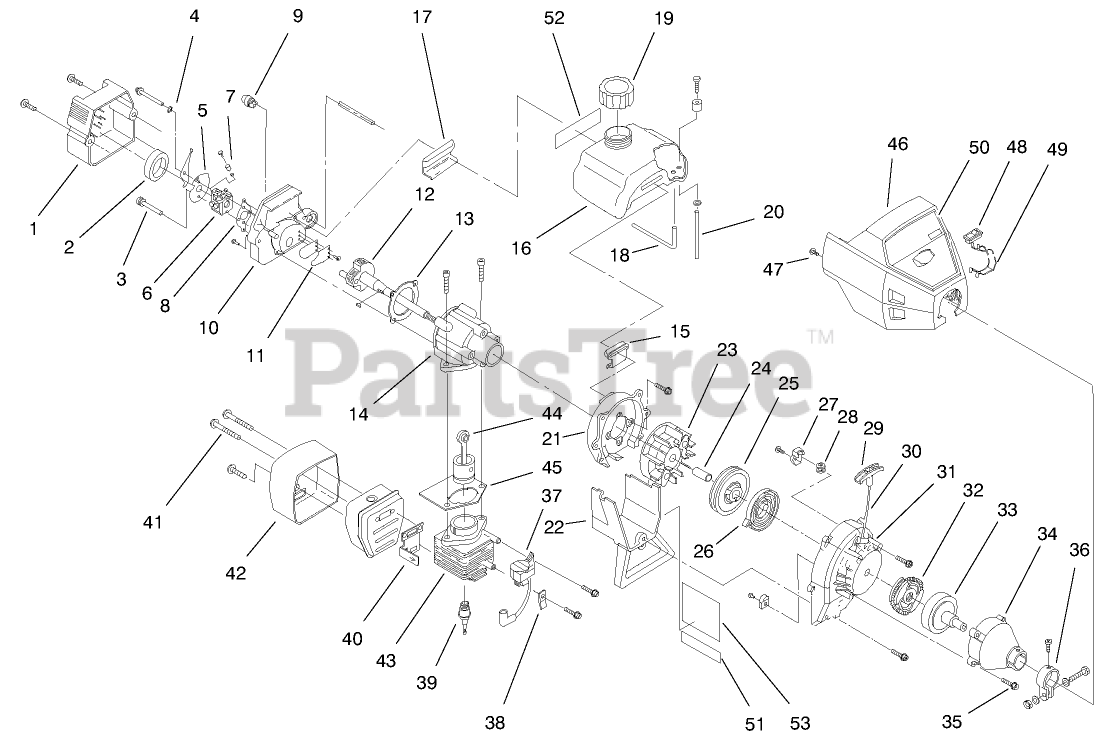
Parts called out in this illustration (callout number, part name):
1	Carburetor/Air Cleaner Asm. (Incl. Ref. #2)
2	FILTER - AIR CLEANER
3	ASSEMBLY - MOUNTING BOLT
4	WASHER - WAVEY
5	LEVER - CHOKE & PLATE
6	Carburetor Asm.
7	THROTTLE ADJ ASM
7	ASM - THROTTLE ADJUSTMENT
8	CARBURETOR GASKET(10 PER PACK)
9	PRIMER & HOSE ASM
10	Carburetor Mount Asm.
11	ASSEMBLY - REED
12	ASM - POWER SHAFT
13	CARB MT GASKET (10-PK)
14	Crankcase Service Asm. (Incl. Ref. #12)
15	FRONT MOUNTING PAD
16	Fuel Tank Asm. (Incl. Ref. #18-20)
17	REAR MOUNTING PAD
18	ASSEMBLY - RETURN LINE
19	FUEL TANK CAP
20	FUEL LINE ASM
21	SHROUD ASM
22	Shroud Extension & Stand
23	FLYWHEEL
24	SPACER
25	RECOIL PULLEY ASM
26	RECOIL SPRING
27	PULLEY RETAINER ASM
28	ROPE GUIDE
29	Handle-Pull
31	ASSEMBLY - STARTER HSG
32	Clutch Rotor Asm.
33	CLUTCH DRUM ASM
34	Clutch Cover Asm.
35	CLUTCH COVER SCREW ASM
36	CLAMP ASM - UPPER
37	Module Asm.
38	GROUND TAB
39	SPARK PLUG
40	GASKET - EXHAUST
41	ASM - MUFFLER MTG BOLT
42	Muffler Asm. (Incl. Ref. #41)
43	ASSEMBLY - CYLINDER
44	PISTON & ROD ASM
45	CYLINDER GASKET
46	COVER - ENGINE
47	Screw
48	SWITCH ASM
49	LEAD WIRE ASM
50	DECAL - TORO
51	Decal-Warning
52	Decal-Fuel & Oil Mix
52	DECAL - CARBURETOR
